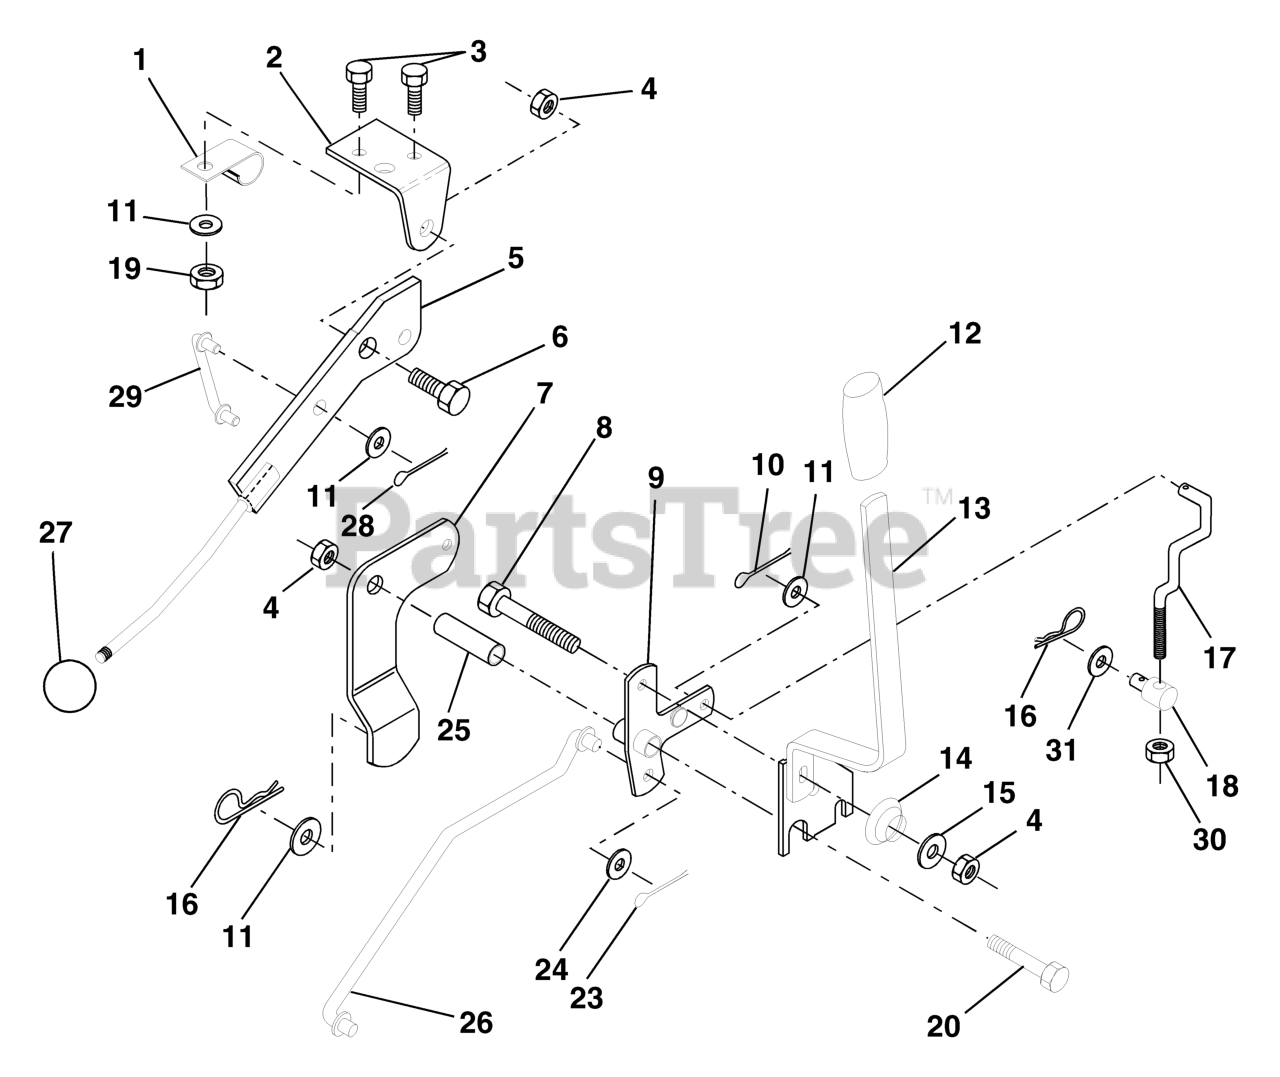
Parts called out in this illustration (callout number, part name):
1	CLIP,INSULATOR
2	BRKT CLUTCH
3	BOLT
5	CLUTCH LEVER
6	BOLT, SHOULDER LT
7	ASSEMBLY MOWER CLUTCH ARM
9	BELLCRANK,LIFT
10	COTTER PIN
11	WASHER
12	HANDLE GRIP
13	LIFT HANDLE ASSY
14	SPRING COMPRESSIO
15	WASHER T
16	SPRING TI
17	LINK LIFT FRT
18	TRUNNION.ADJUSTABLE.3/8-16
19	NUT.CROWNLOCK.1/4
23	PIN COTTER
24	WASHER GT
25	TUBE SPACER
27	KNOB T (3/8 HOLE)
28	COTTER PIN
29	LINK MOWER CLUTCH
30	NUT
31	WASHER
